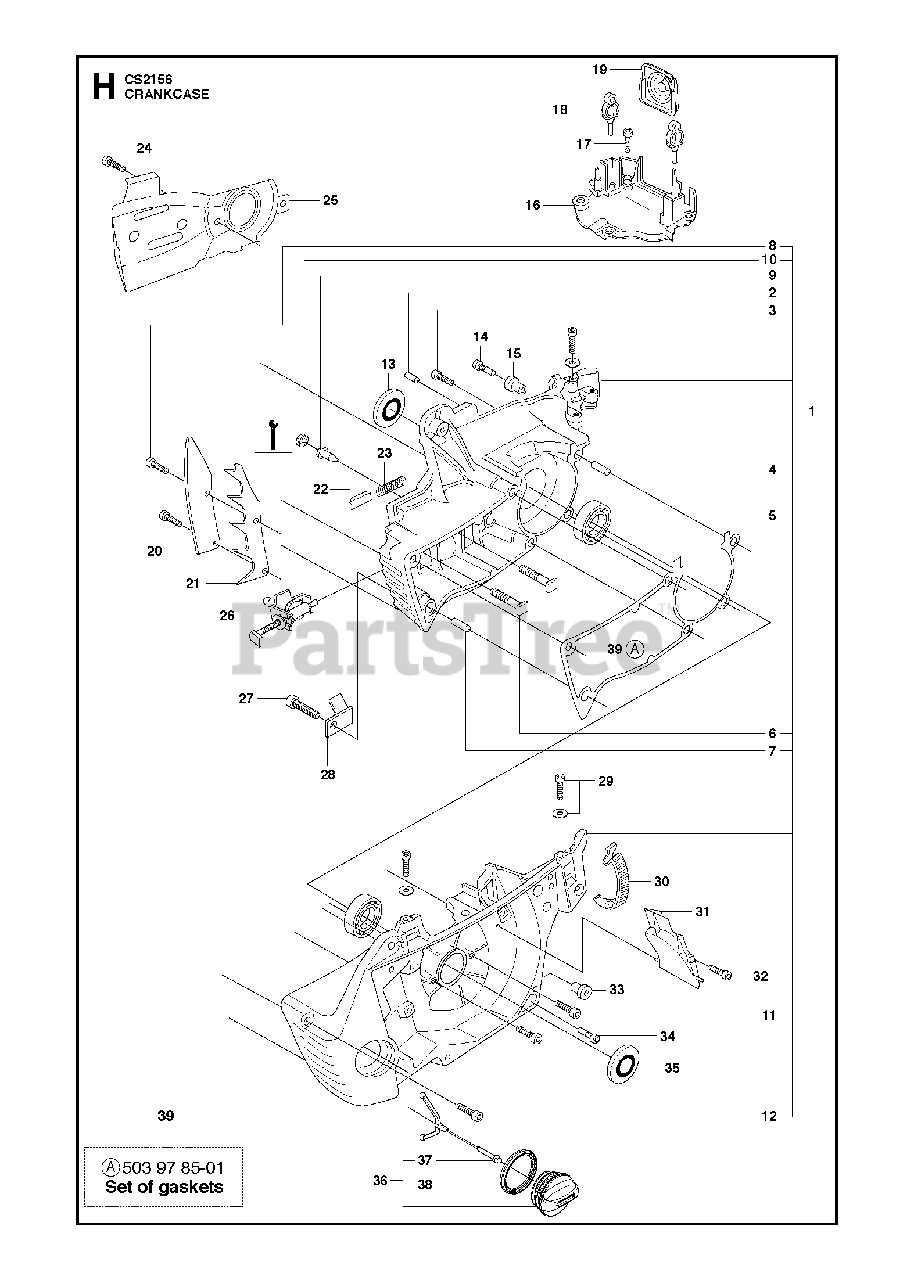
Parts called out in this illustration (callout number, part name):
1	CRANKCASE CPL
2	PIN
3	SCREW
4	SLEEVE
5	BALL BEARING-6202-C3 SKF
6	BOLT
7	SLEEVE
8	SCREW
9	VALVE-CHECK (DUCKBILL)
10	PLUG
11	SCREW
13	SEAL RING
15	MOVEMENT LIMITER
16	CARBURETOR AREA BASE
21	FELLING DOG
23	LOCK SPRING
26	CHAIN TENSIONER
28	CHAIN CATCHER
33	MOVEMENT LIMITER
35	SEAL RING
36	TANK CAP
37	HOLDER
38	SEALING
39	GASKET SET
